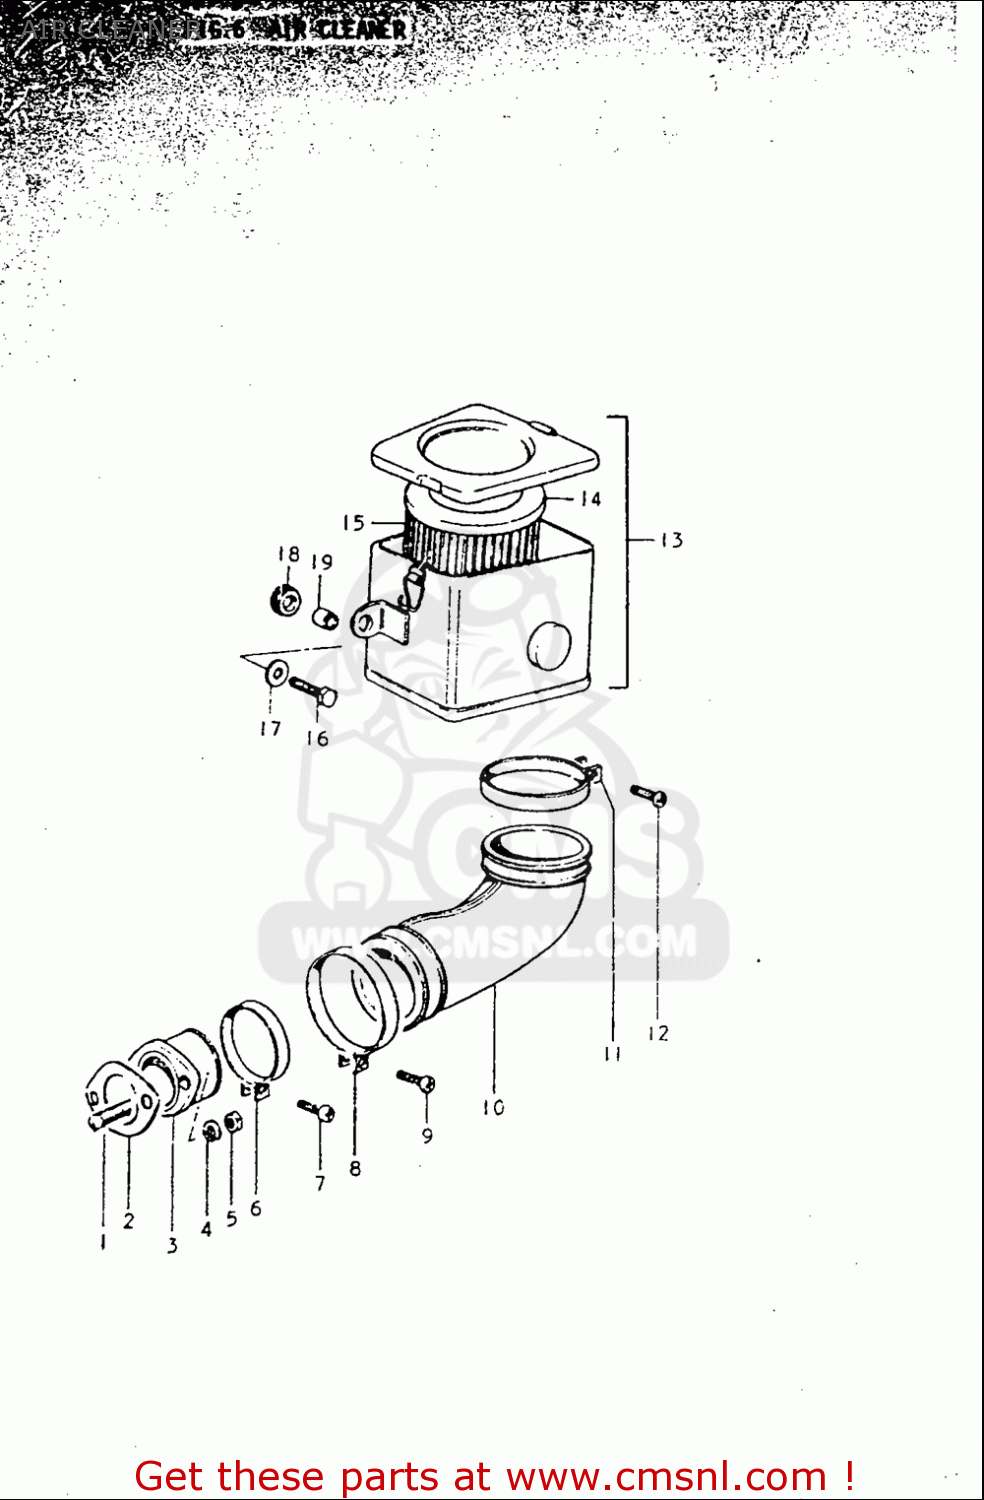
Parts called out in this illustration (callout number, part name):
1	STUD BOLT
2	GASKET,CARBURETOR (NAS)
3	PIPE,INTAKE
4	WASHER,LOCK
5	NUT
8	CLAMP
11	CLAMP
16	BOLT
17	WASHER(6.5X20X1.2)
18	CUSHION
19	SPACER,6.5X9X7
